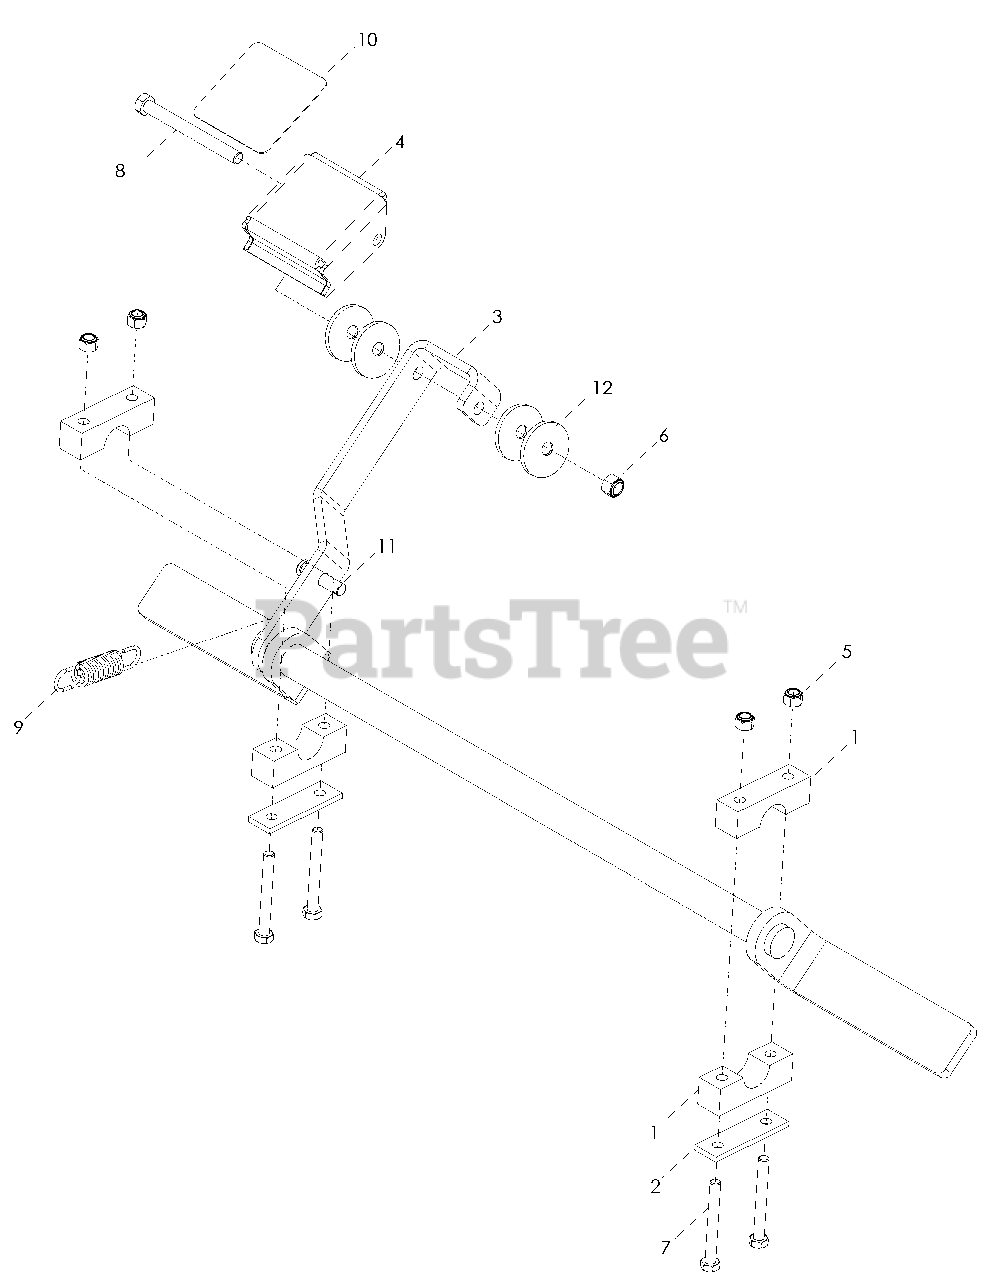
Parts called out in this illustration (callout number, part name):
1	PILLOW BLOCK
2	REINFORCEMENT BAR
3	PARK BRAKE
5	NUT 5/16-18 HEX NYLOC
6	NUT 3/8-16 HEX NYLOC
7	HCS 5/16-18 x 2 3/4
8	HCS 3/8-16 x 3 3/4
9	SPRING, EXTENSION
10	PAD, ANTI-SKID
11	PIN, CLEVIS 3/8 x 1 1/2
12	WASHER, FRICTION
